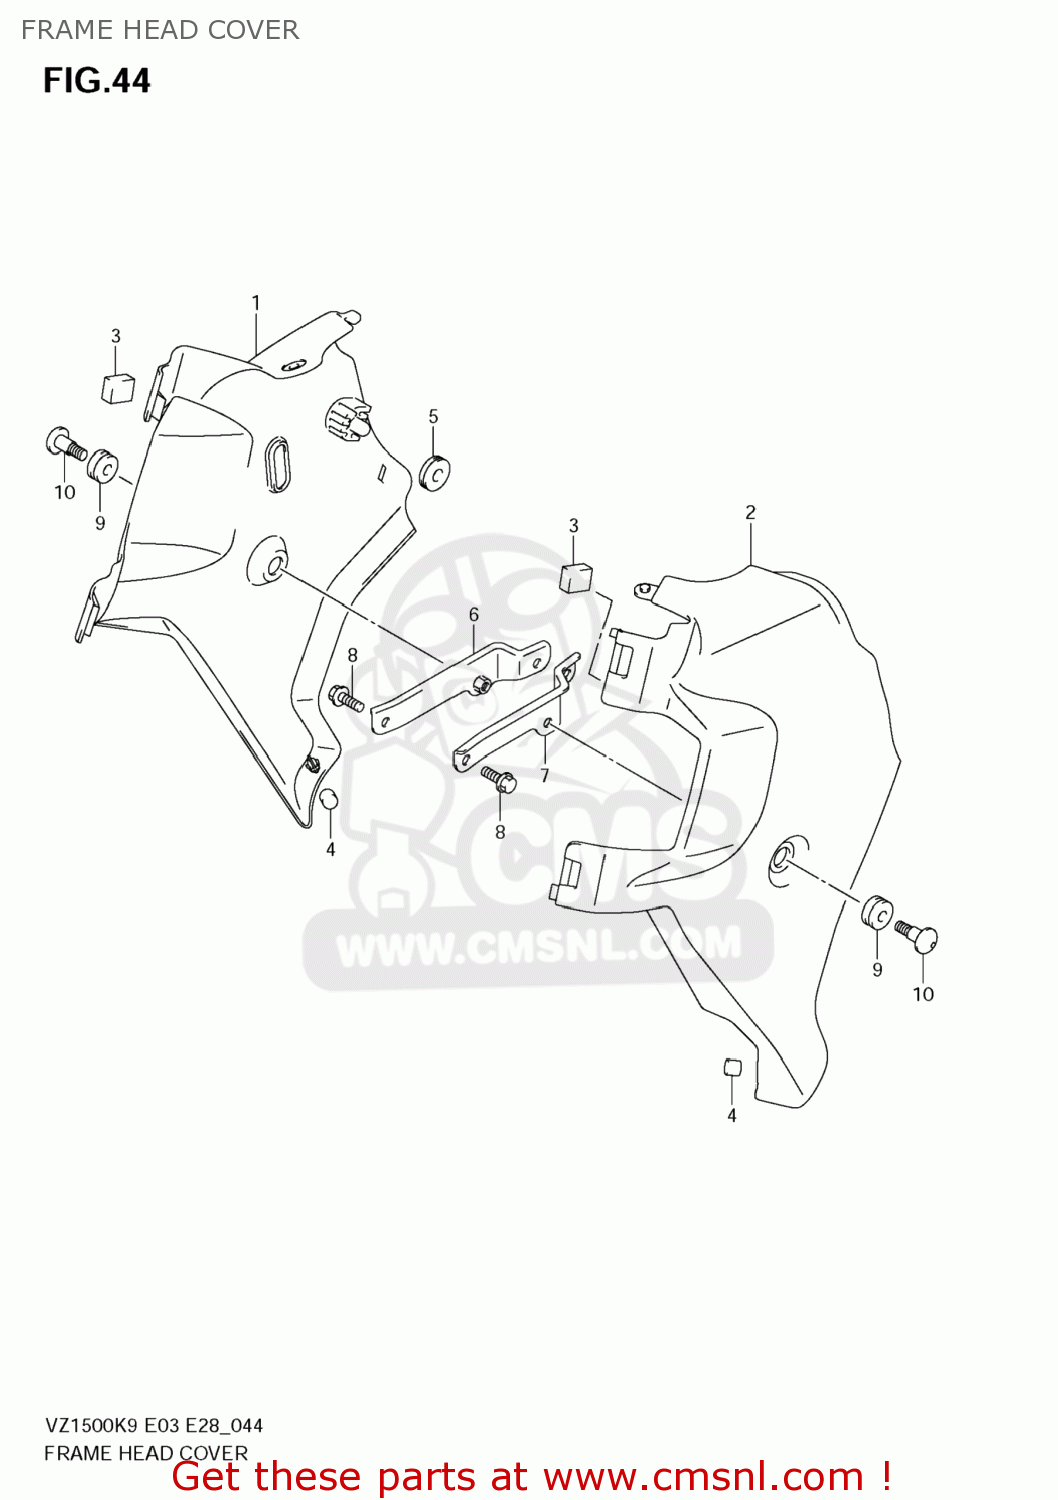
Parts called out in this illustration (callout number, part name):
1	COVER,FRAME HEAD,R
2	COVER,FRAME HEA
3	CUSHION,RADIATOR COVER INNER
4	CAP(OD:12.3)
5	CUSHION
6	PLATE,FRAME HEAD COVER,R
7	PLATE,FRAME HEAD COVER,L
8	BOLT
9	CUSHION
10	BOLT(6X20)
